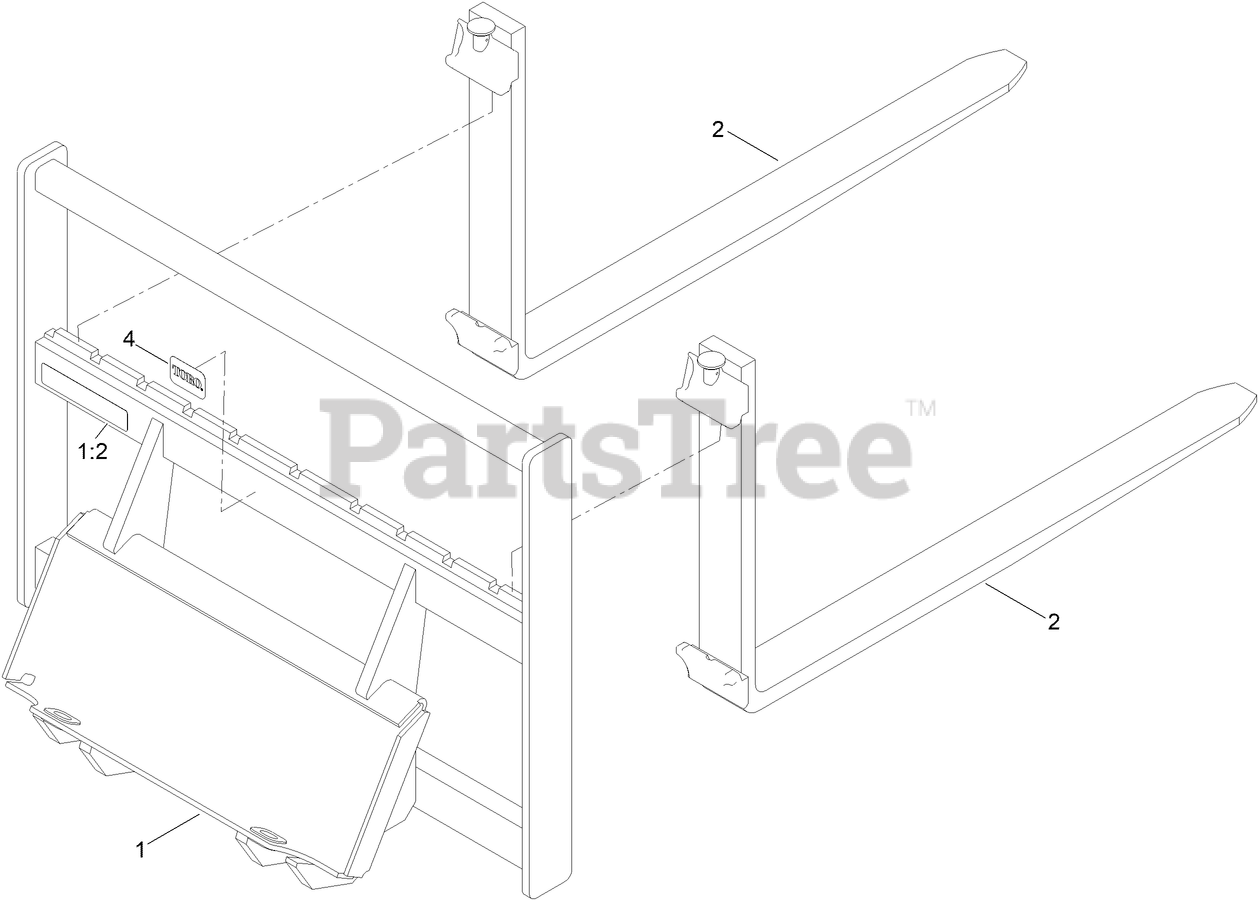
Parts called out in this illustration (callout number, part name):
1	FORK FRAME ASM,
1:2	DECAL-CAPACITY,
2	TINE-FORK
4	DECAL
